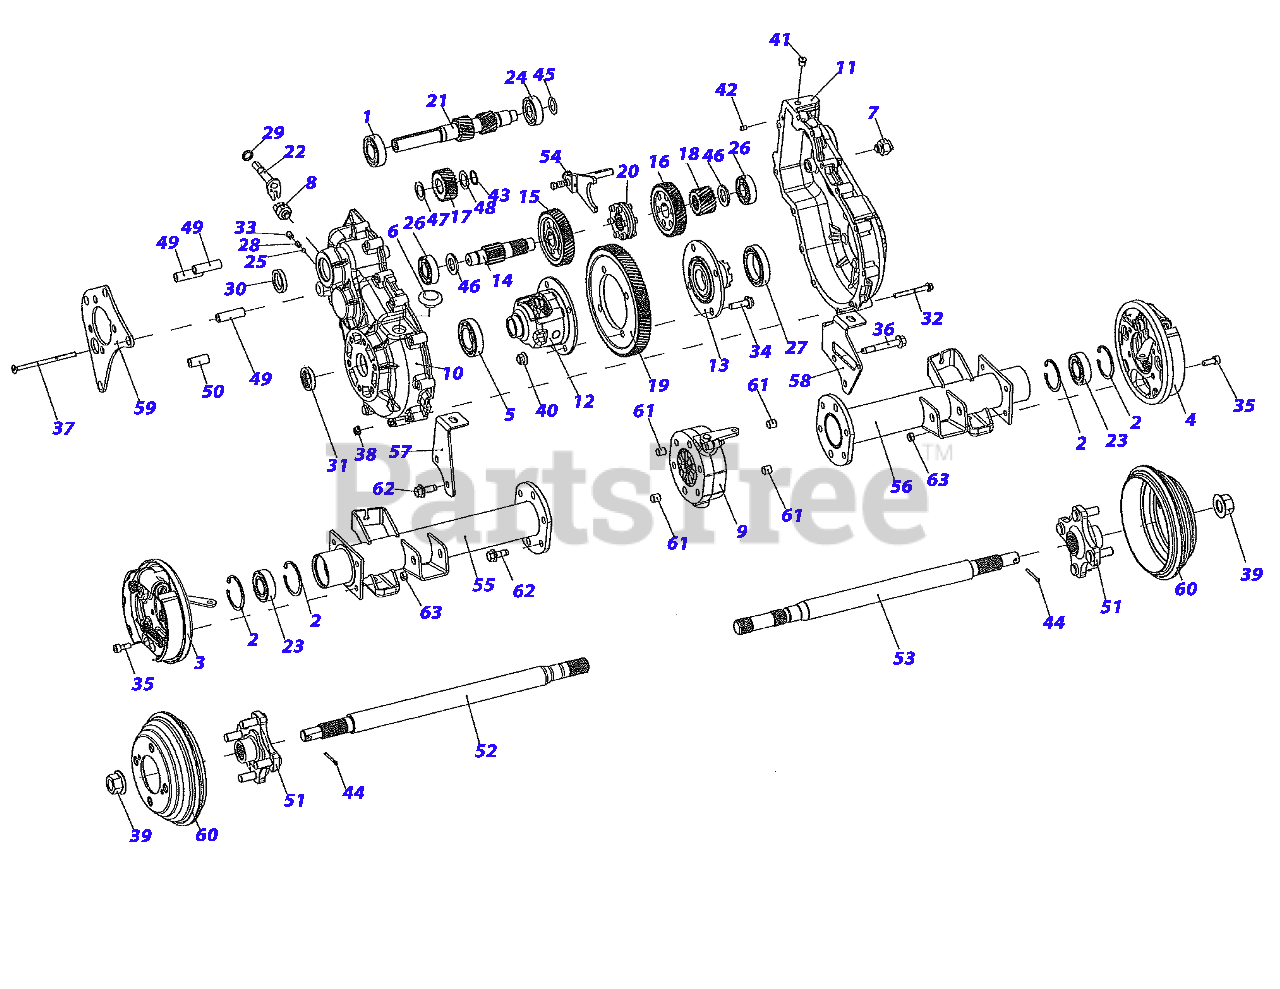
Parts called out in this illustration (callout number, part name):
1	BALL BEARING
2	RETAINING RING
3	BRAKE ASSEMBLY (RH)
4	BRAKE ASSEMBLY (LH)
5	BALL BEARING
9	DIFF LOCK HOUSING ASSEMBLY
10	HOUSING AND SHAFT ASSEMBLY
11	CASE HOUSING RH
12	DIFFERENTIAL ASSEMBLY
13	FLANGE 1/2-DIFF CA
14	INTERMEDIATE SHAFT
15	FORWARD GEAR ASSEMBLY
16	REVERSE GEAR ASSEMBLY
17	IDLER GEAR ASSEMBLY
18	PINION GEAR
20	GEAR-CLUTCH
21	INPUT SHAFT
22	SHIFT ACTUATOR ASSEMBLY
23	BALL BEARING
24	BALL BEARING
25	DETENT BALL
26	BALL BEARING
27	BALL BEARING
28	COMPRESSION SPRING
33	SET SCREW 5/16-18 x .500
35	CAP SCREW M8 x 1.15 x 10
36	FLANGE HD CA SCREW
39	HEX FLANGE NUT 3/4-16
43	RETAINING RING
44	COTTER PIN 1/8 x 1.15
46	FLAT SPACER
47	THRUST WASHER
48	THRUST WASHER
49	MOUNTING COVER SPACER
50	MOUNTING COVER SPACER
51	WHEEL HUB ASSEMBLY
52	AXLE SHAFT ASSEMBLY
53	REAR AXLE SHAFT ASEMBLY
54	SHIFT FORK ASSEMBLY
55	TUBE ASSEMBLY (LH)
56	TUBE ASSEMBLY (RH)
57	EXHAUST BRACKET
58	DIFF LOCK BRACKET
59	CVT COVER ASSEMBLY
61	LOCATING BUSHING
62	FLANGE SCREW
